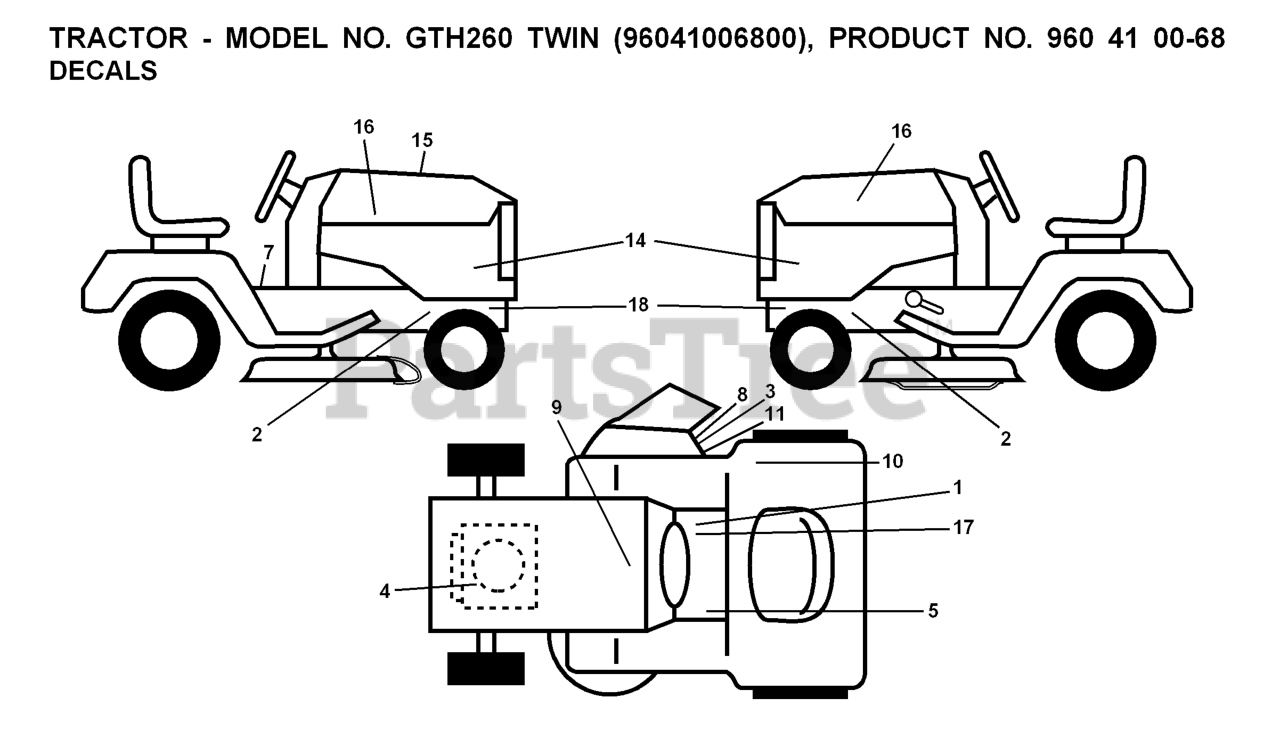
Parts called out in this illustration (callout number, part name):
1	HEAD ASSY SPEED
2	SCREW #10-24 X 5/8
3	PLATE.END.CHAIN.ASM.PNT.ORANGE
4	Screw 5/16-18 x 1/2 Hex, Self Tapping 5/16-18 x 1/2
5	THRUST WASHER
6	ARM, AUGER CONTROL
7	CLEVIS PIN
8	PLATE.SHIFTER.BZP
9	BOLT.SHOULDER.3/X.25
10	BRACKET.SHIFTER.PLATE.BZP
11	NUT.HEX.FLANGE.1/4
12	PLATE.CLUTCH.BZP
13	BRACKET.CLUTCH.PLATE.BZP
14	LINK, SPEED CONTROL
15	RETAINER CLIP
16	CONTROL.SHAFT.ASM
17	ROD.CLUTCH.SWING.PLATE
18	SPRING RETAINER
19	YOKE.SHIFTER.SPEED
20	ROD.PIVOT.SHIFTER
21	KLIP RING TI
22	SPRING.TRACTION.RETURN
23	NUT.LOCK.5/16-18
24	BEARING FLANGE BALL
25	NUT.CENTERLOCK.5/16-
26	PLATE.RUBBER.WHEEL
27	RING.RUBBER.2-STG.SNW.DRV.WH
28	TRUNNION BEARING ASSY
29	HUB, RUBBER WHEEL
30	BOLT
31	RETAINING RING (2 2)(3 2)
32	SHAFT.HEX.W/SPOCKET
33	CHAIN.DRIVE.SNOWTHROWER.#420
34	SPROCKET.WELDMENT
35	SHIFTER BRACKET
36	SPRING, BIAS
37	ROD.PIVOT.SWING.PLATE.SNOW
38	E-RING.RETAINER.REINFORCED.375
39	SCREW, HEX HEAD, TAPPING
40	PAN.BOTTOM.PLASTIC
41	BRACKET.TRACTION.SPRING.
42	RP.PULLEY.PLATE.ASM.DRIVE
43	SPRING.TRACTION.IDLER
44	SPRING, BRAKE
45	SHAFT.FRICTION.PULLEY.SNOW
46	PULLEY.PLATE.ASM.DRIVE
48	RP PULLEY.HALF.TRACTION
50	SPACER BEARING
51	PLATE.SWING.DRIVE.BLACK
52	FLANGED LOCKNUT 3/8-16 ZINC
53	BOLT.HEX.HD.WASHER.5/16-18X.75
54	BOLT.5/16HEX.WHS.HD
